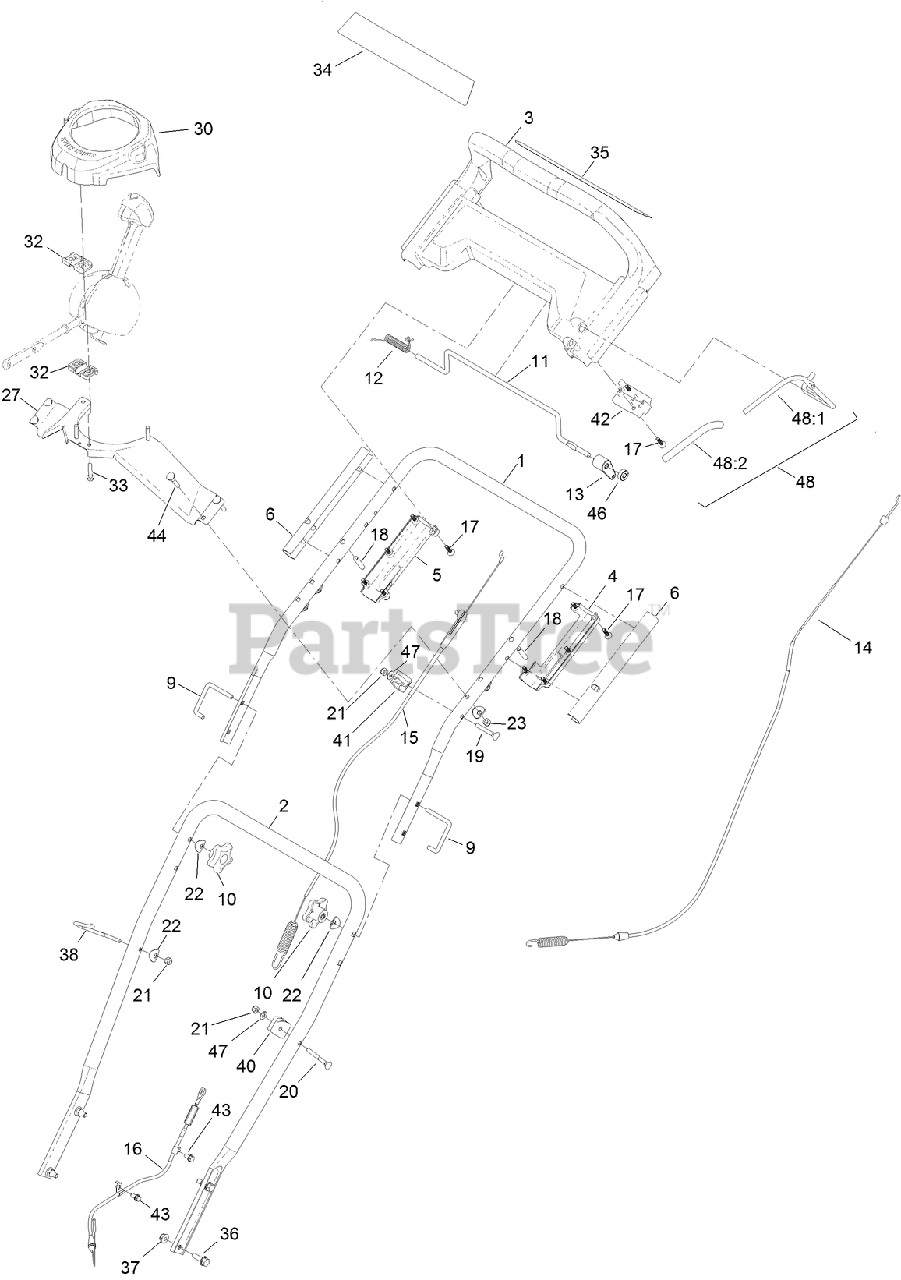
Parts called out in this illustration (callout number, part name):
1	HANDLE-UPPER
2	HANDLE-LOWER
3	HANDLE
4	HANDLE-BOTTOM, LH
5	HANDLE-BOTTOM, RH
6	SLEEVE HANDLE
10	KNOB-HANDLE
13	LEVER-TRACTION
14	CABLE-TRANSMISSION
15	CABLE-ROTOR, UPPER
16	CABLE-ROTOR, LOWER
18	PIN-DOWEL
19	SCREW
20	SCREW-HANDLE
21	NUT-LOCK, NI
22	WASHER
23	NUT-LOCK, NI
27	BRACKET-CHUTE, CONTROL
30	COVER TOP
32	SUPPORT-ROD
33	SCREW-PLASTITE
34	DECAL-DISPLAY
35	DECAL-CONTROL, PANEL
36	SCREW-HHF
37	NUT-HF, NI
38	GUIDE-ROPE
40	ANCHOR-CABLE, UPPER
41	CABLE-GUIDE
42	BAIL-MOUNT
43	SCREW-HWH
44	SCREW-HANDLE
46	SPACER
47	WASHER-FLAT
48	BAIL ASM
48:1	BAIL-AUGER
48:2	COVER-BAIL
